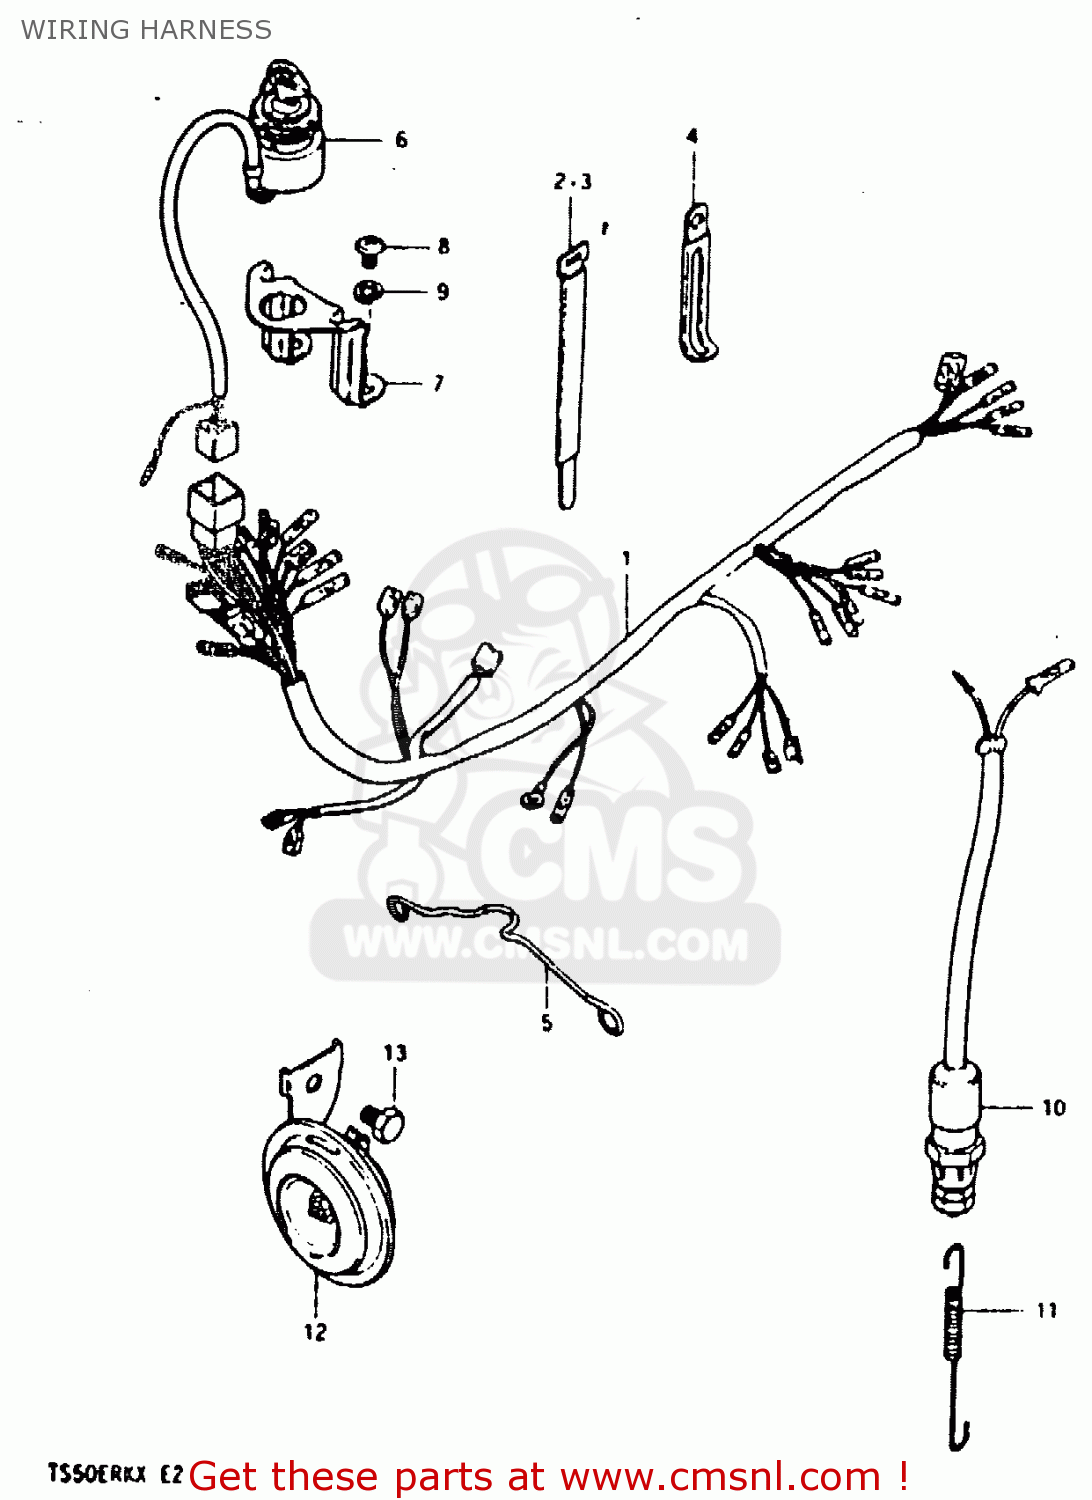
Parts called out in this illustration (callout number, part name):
1	WIRING HARNESS
2	CLAMP
3	CLAMP
4	CLAMP
5	CLAMP
6	SWITCH ASSY, IGNITION
7	BRACKET,IGNITION SWITCH
8	SCREW
9	LOCK WASHER
10	SWITCH ASSEMBLY,STOP LAMP
11	SPRING
12	HORN
13	BOLT
